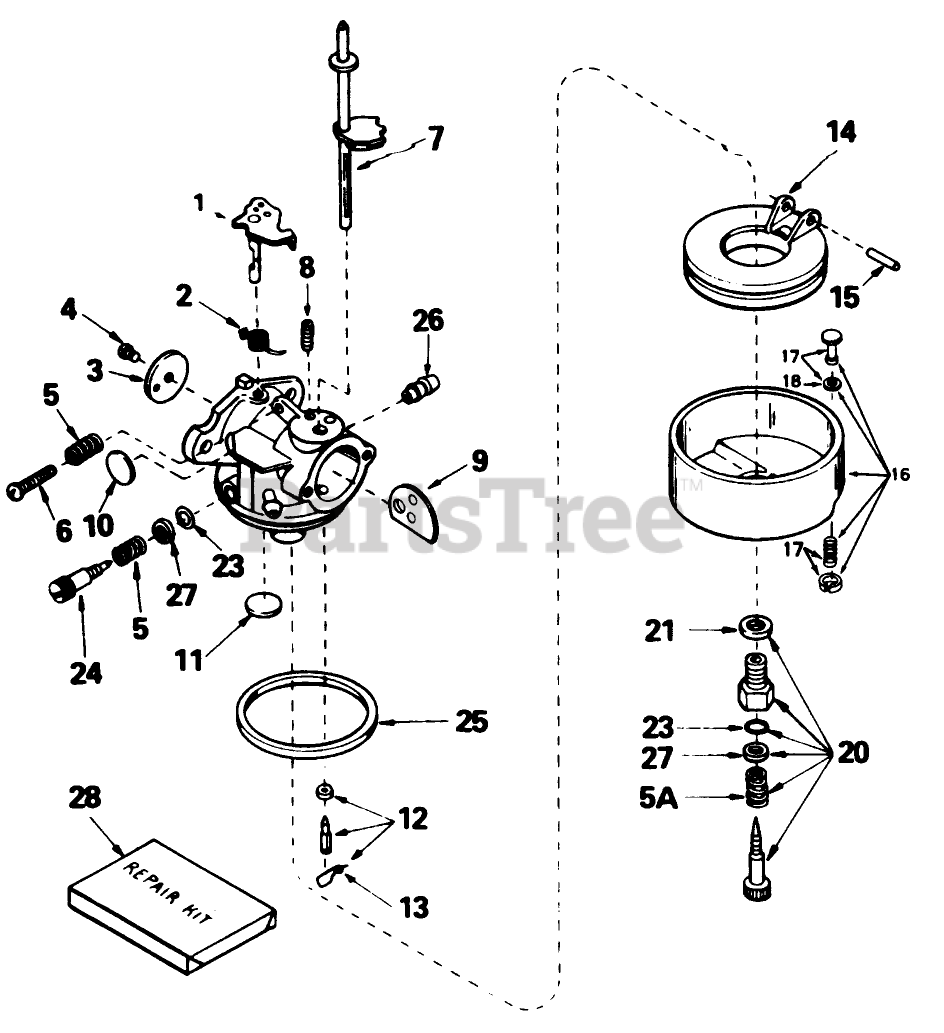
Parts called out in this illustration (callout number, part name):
1	Shaft/Lever-Throttle
2	Spring-Return, Throttle
3	Shutter-Throttle
4	Screw-Shutter
5	Spring-Tension
5A	Spring
6	Screw-Throttle Crack Screw / Idle Speed
7	Shaft-Choke
8	Spring-Positioning, Choke
9	Shutter-Choke
10	Plug-Welch, Idle Mixture Well
11	Plug-Welch, Atmospheric Vent
12	Inlet Needle, Seat Clip Assy. (Incl. No. 13)
13	Clip-Spring
14	Float
15	Shaft-Float
16	Float Bowl Asm. (Incl. Ref. # 32, 33)
17	Bowl Drain ASM
18	Gasket-Plunger, Drain
20	Adjustment Screw Assy., Main (Incl. Nos. 5A, 21 23)
21	Washer-Bowl Nut
23	ORing
24	Screw-Idle
25	O Ring-Bowl, Float
26	Fitting-Fuel
27	Washer
28	Repair Kit (Incl. items marked *)
